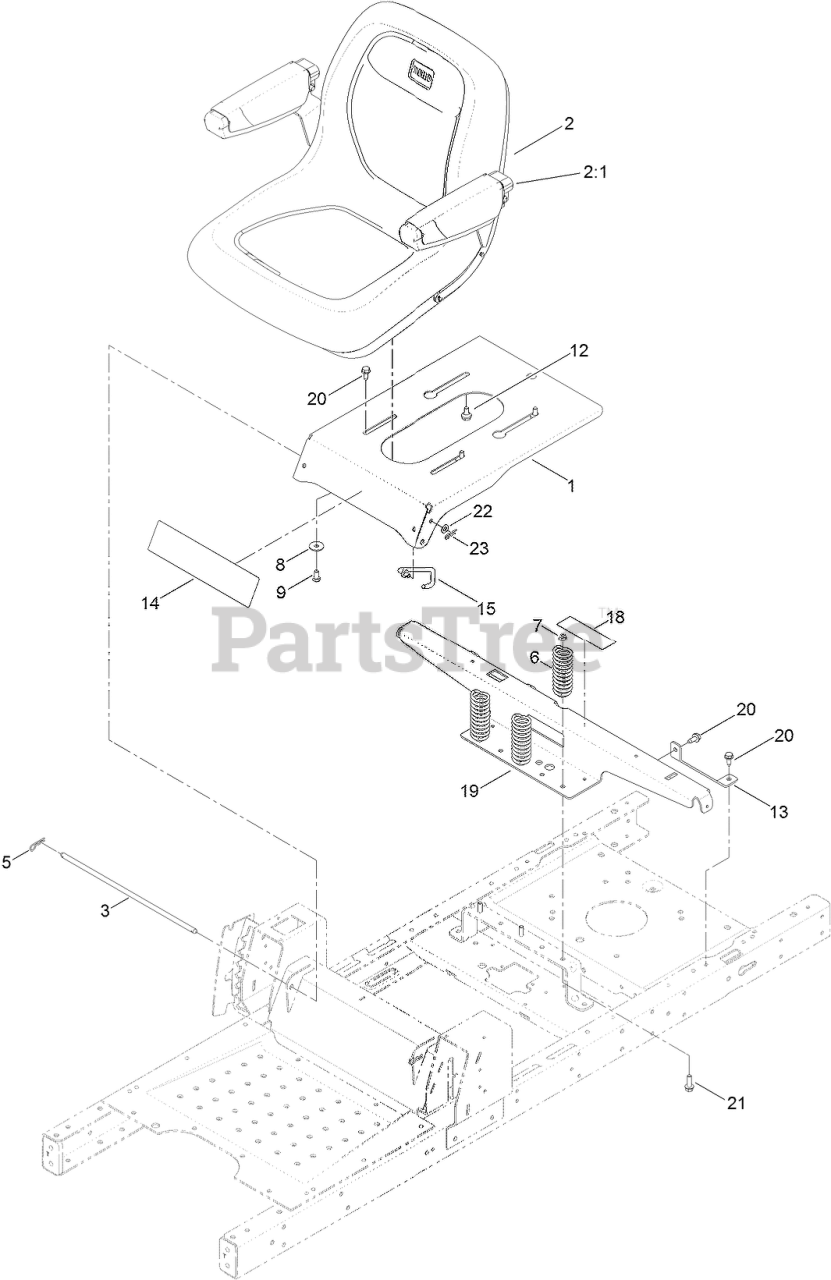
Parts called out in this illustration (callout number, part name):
1	PAN-SEAT
2	SEAT-18 Inch
2:1	ARMREST KIT (MILSCO)
3	ROD-PIVOT, NARROW
5	PIN-COTTER
6	SPRING-COMPRESSION
7	NUT-HF, NI
8	WASHER-PIVOT
9	SCREW-HH
12	BOLT-SHOULDER
13	SUPPORT-TANK, REAR
14	DECAL-TIMECUTTER
15	STOP-SEAT
18	DECAL-SERVICE, CE
19	SUPPORT-POD
20	SCREW-HWHTF
21	SCREW-HHF
22	WASHER-PLAIN
23	PIN-COTTER
